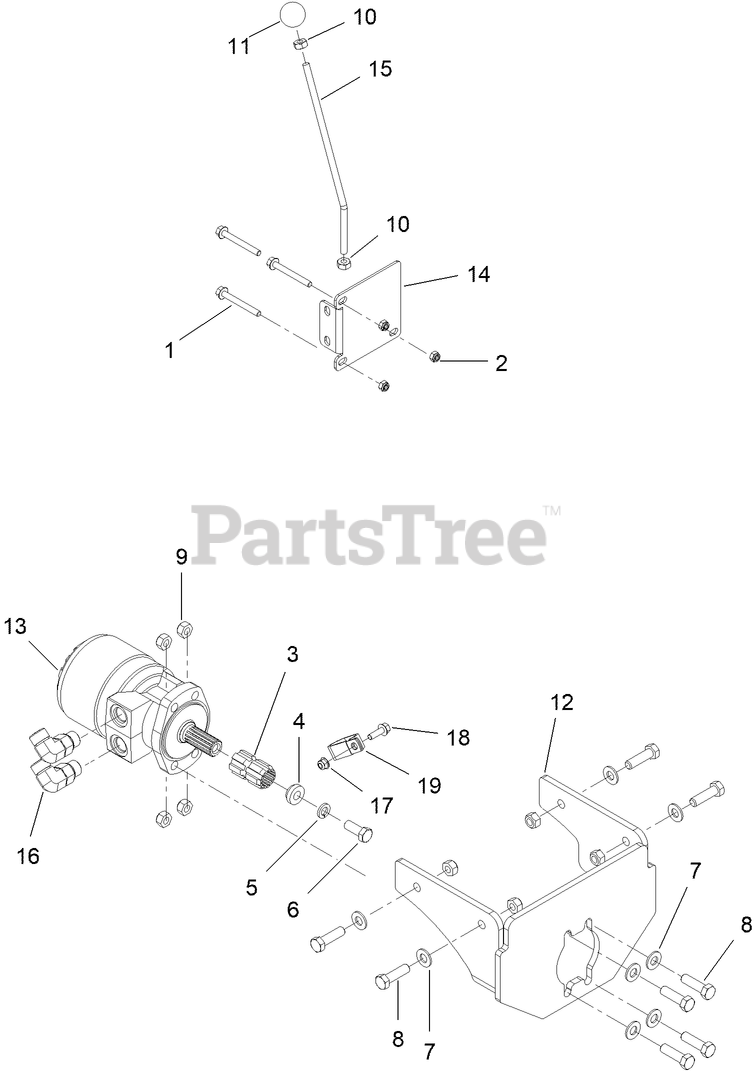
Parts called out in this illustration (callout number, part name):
1	SCREW-HHF
2	NUT-LOCK, NI
3	ADAPTER
4	RETAINER-ADAPTER
5	WASHER-LOCK
6	SCREW ( .50-20UNFX1.25 GRADE 8)
7	WASHER-FLAT
8	SCREW-HH
9	LOCKNUT
11	KNOB-ROUND
12	MOUNT - HYDRABORE
13	HYD MOTOR ASM
14	BRACKET-HYDRO VALVE
16	CONNECTOR (10S-10O90)
17	NUT-HF, NI
18	SCREW-HHF
19	CLAMP-R, DOUBLE
